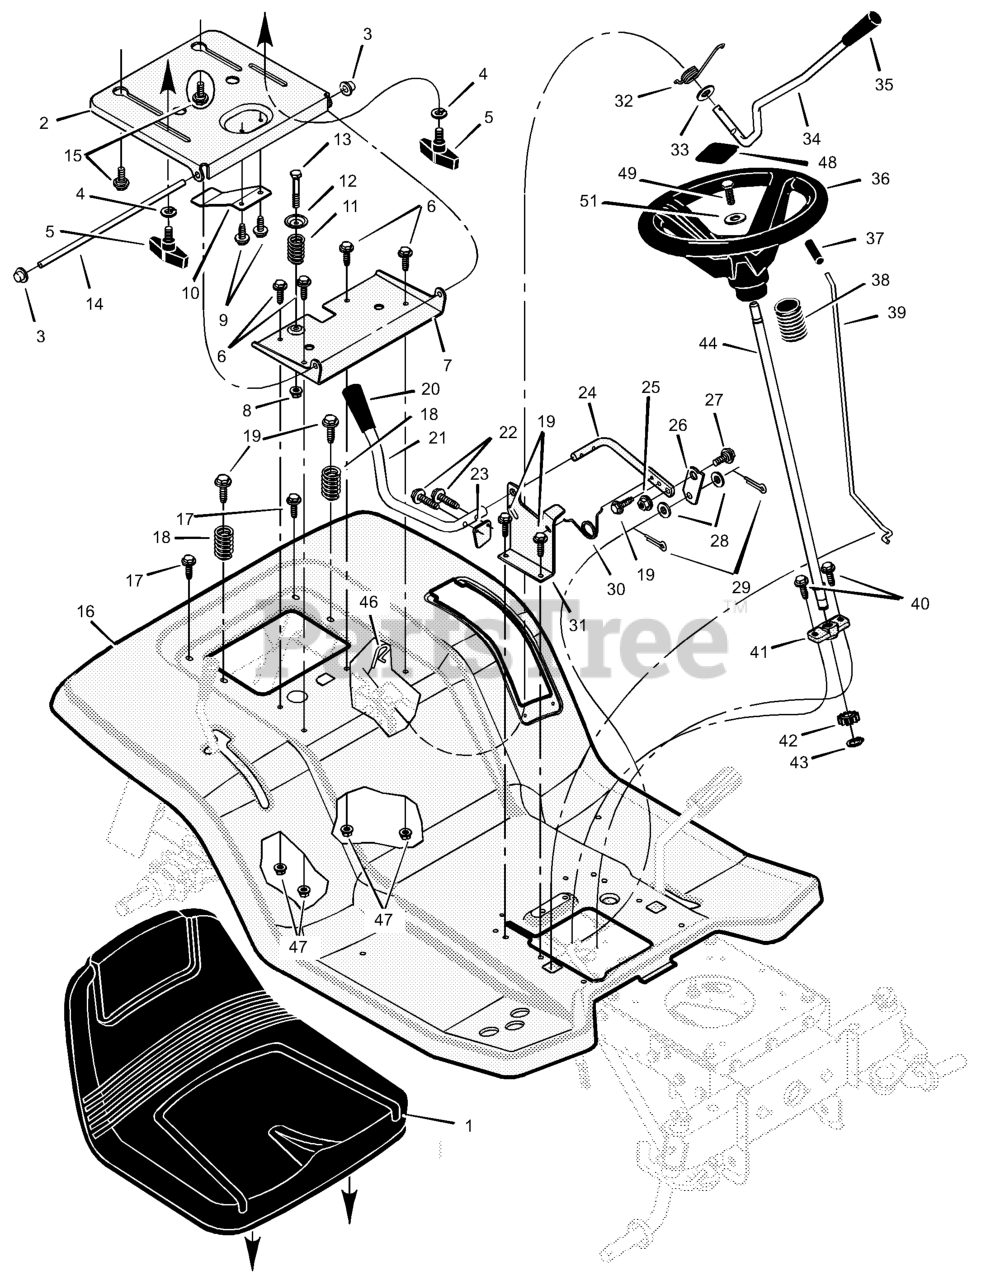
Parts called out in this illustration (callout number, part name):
1	Seat
2	Support, Seat
3	Push-On Cap
4	Washer
5	Bolt, Wing
6	Bolt
7	Bracket, Pivot
8	Nut
10	Spring, Leaf
11	Spring
12	Washer, Cup
14	Rod, Pivot
15	Bolt, Shoulder
16	Deck, Seat
20	Grip
21	Handle, PTO
22	Screw, Hex
23	Paddle, Switch
24	Lever, PTO
25	Nut
26	Link, PTO
27	Shoulder, Bolt
29	Pin, Cotter
31	Bracket, PTO
34	Handle, Lift
35	Grip
36	Wheel, Steering
38	Bellows
39	Rod, Parking Brake
41	Bearing, Lower
42	Gear, Pinion
44	Shaft, Steering
46	Pin, Cotter
47	Nut
48	Insert, Steering Wheel
49	Screw, Hex
51	Washer
